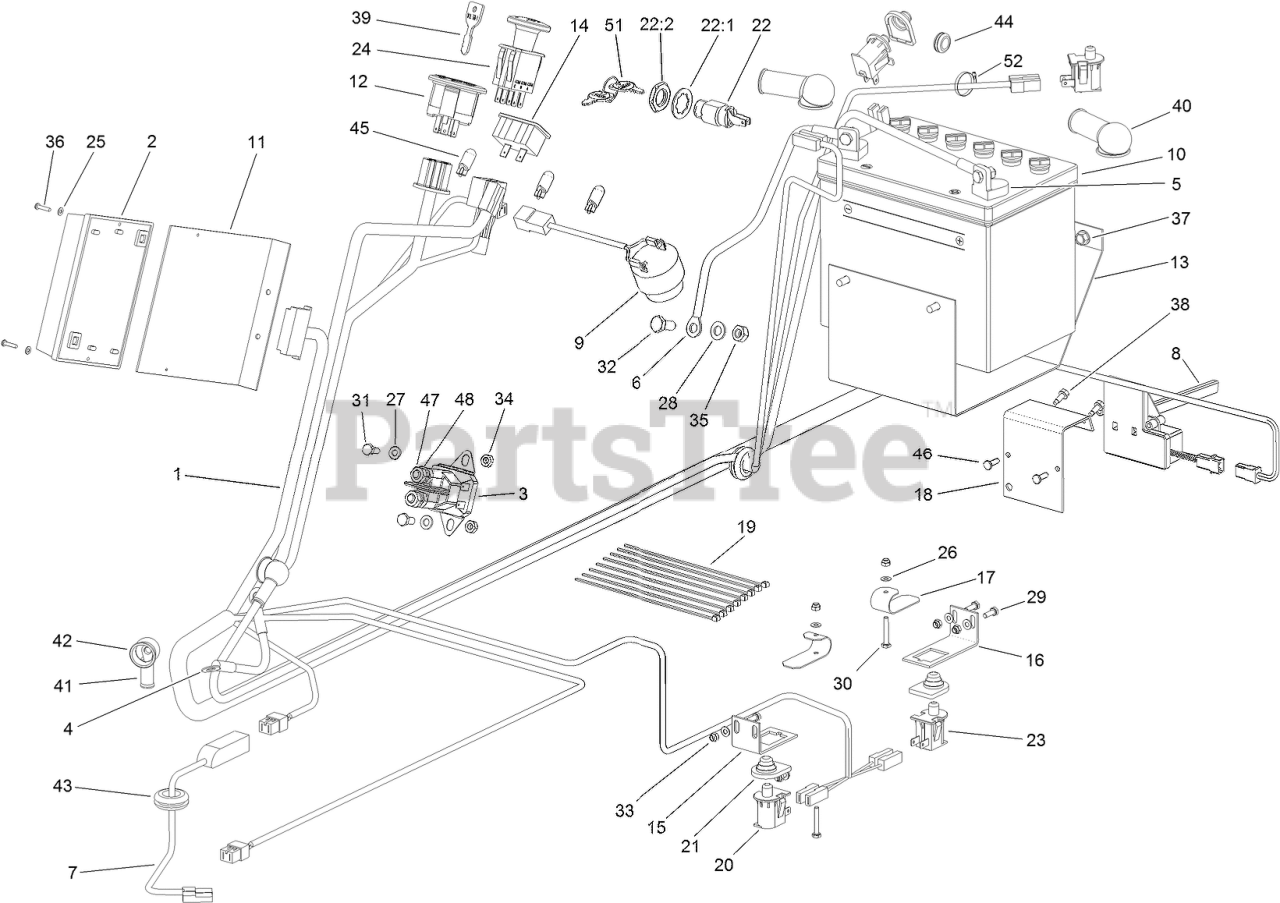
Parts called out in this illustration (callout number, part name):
1	HARNESS-WIRING
2	MODULE-CONTROL
3	SOLENOID
4	CABLE-STARTER
5	CABLE-BATTERY, POSITIVE
6	CABLE-BATTERY, NEGATIVE
7	HARNESS-CLUTCH
8	OVERLOAD SWITCH ASM
9	BUZZER
10	BATTERY-12V
11	HOLDER-MODULE
12	SWITCH-IGNITION
13	HOLDER-BATTERY
14	HOURMETER
15	HOLDER
16	HOLDER
17	LEVER-SPRING
18	BRACKET-SWITCH
19	TIE-CABLE
20	SWITCH-DELTA
21	COVER-PROTECTIVE
22	STARTER SWITCH ASM
22:1	WASHER-TOOTH, INTERNAL
22:2	NUT-HH
23	SWITCH-DELTA
24	SWITCH-PTO
25	WASHER
26	WASHER
27	WASHER
28	WASHER-PLAIN
30	SCREW-HEX
31	SCREW-HH
32	SCREW-HH
33	NUT-HEX
34	NUT-LOCK
35	NUT-LOCK, NI
38	SCREW-TAP
39	KEY-IGNITION
40	BOOT-RUBBER
41	BOOT-RUBBER
42	NUT-HHF
43	BUSHING
44	BUSHING
46	Screw
47	NUT-HHF
48	WASHER-SPRING
51	KEY-IGNITION
52	CLIP-SNAP
